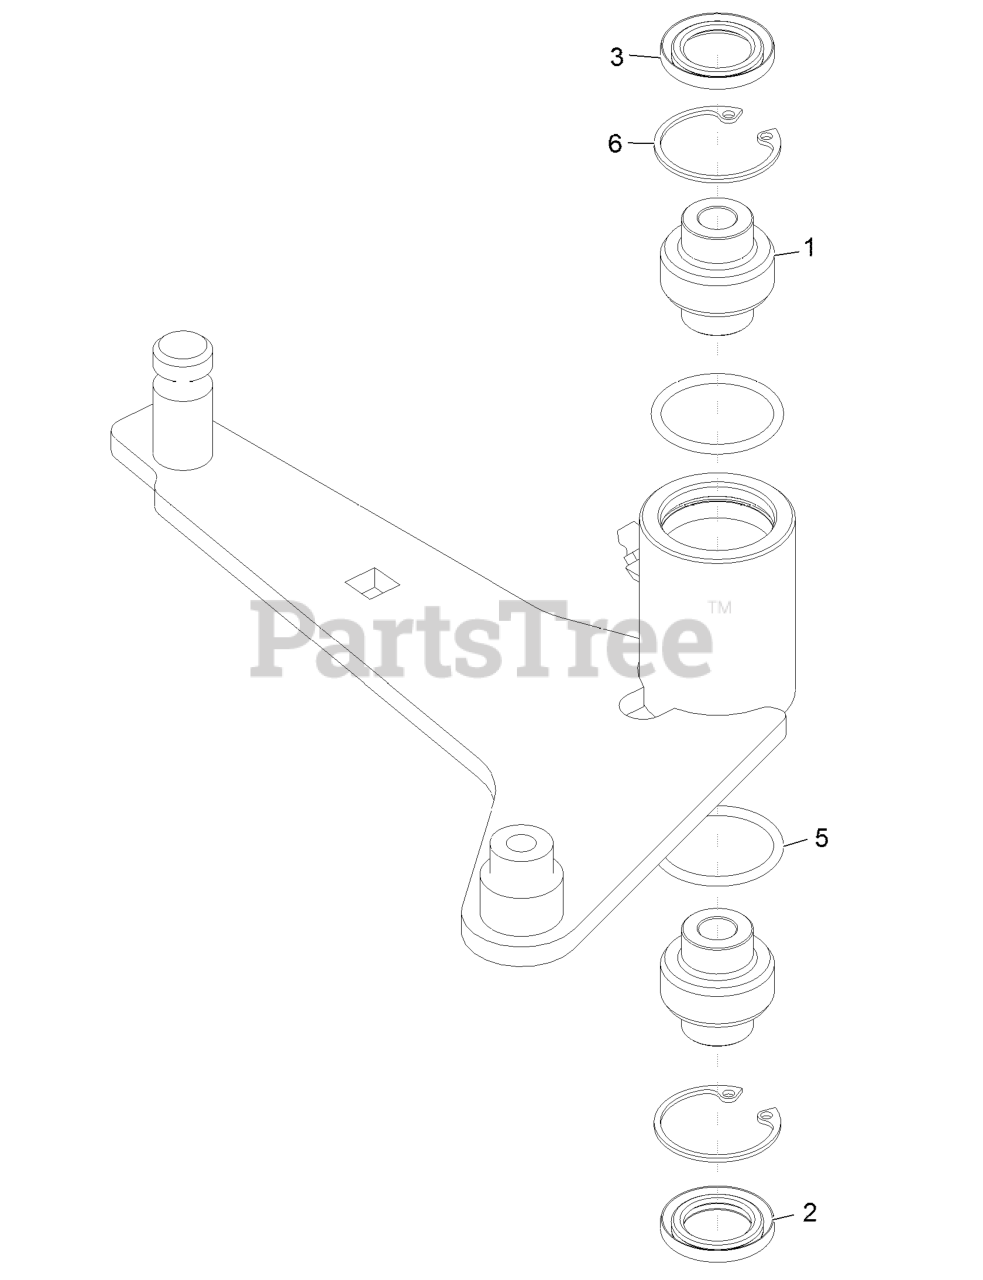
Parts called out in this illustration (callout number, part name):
1	BEARING-SPHERICAL
2	SEAL-LIP, DOUBLE
3	SEAL-LIP, SINGLE
6	RING-SNAP
